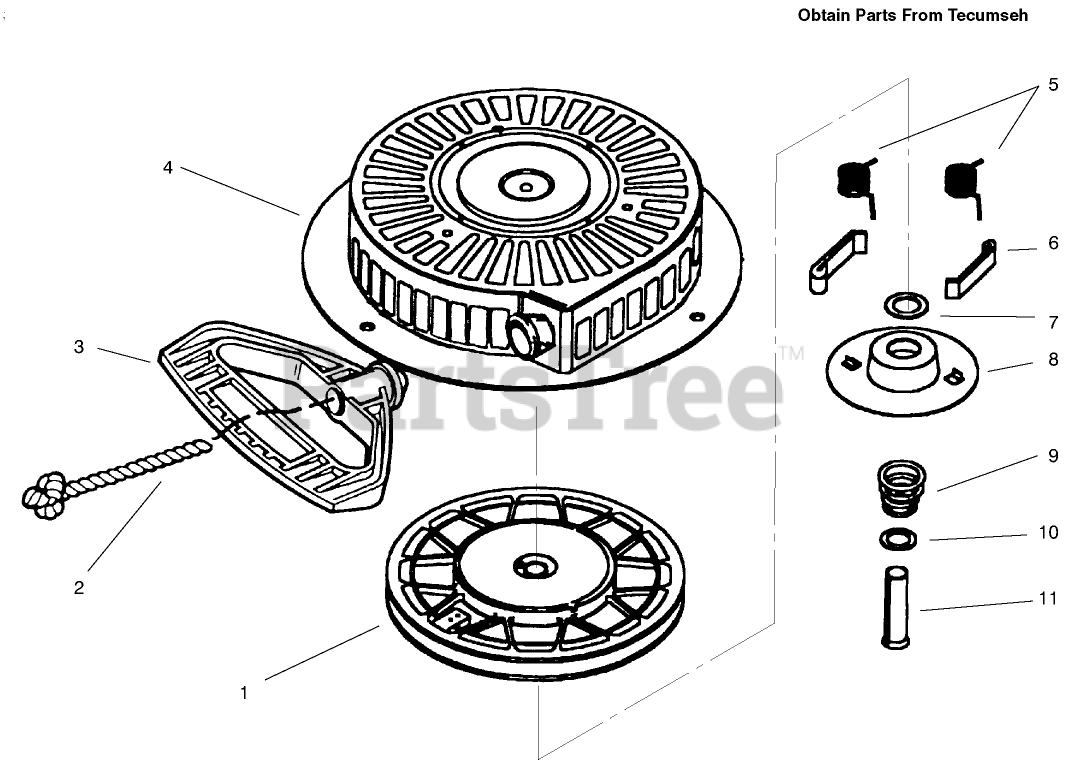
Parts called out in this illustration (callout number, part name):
1	Pulley and Rewind Spring ASM
2	Rope-Starter (98 cut to length)
3	Handle-Starter, Mitten Grip
4	Spring, Pawl
5	Spring-Dog
6	Dog-Starter
7	Washer
8	Retainer
9	Spring-Brake
10	Washer
11	Pin, Spring (Incl. Ref. #7)
